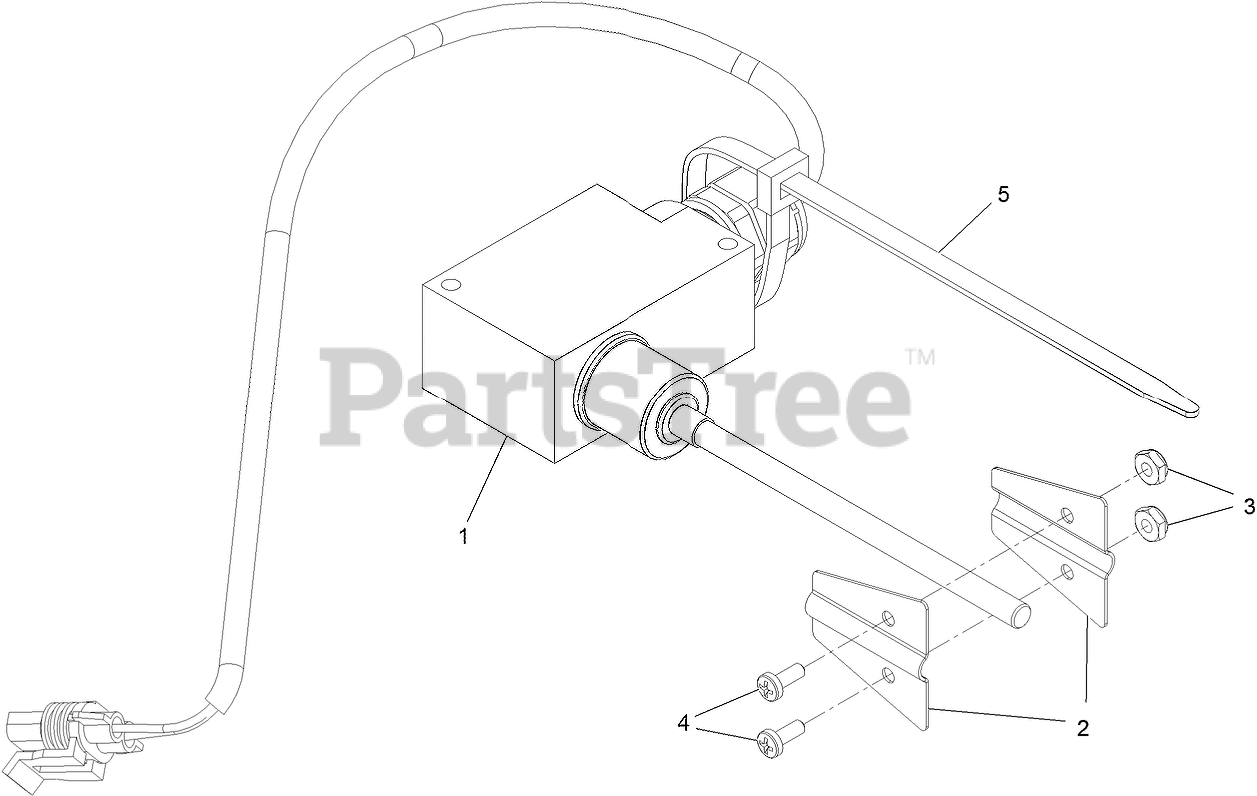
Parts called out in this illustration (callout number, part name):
1	FILL SENSOR WIRE KIT
2	FLAG- SENSOR, FILL
3	NUT-HEX
4	SCREW-PAN
5	TIE-CABLE
